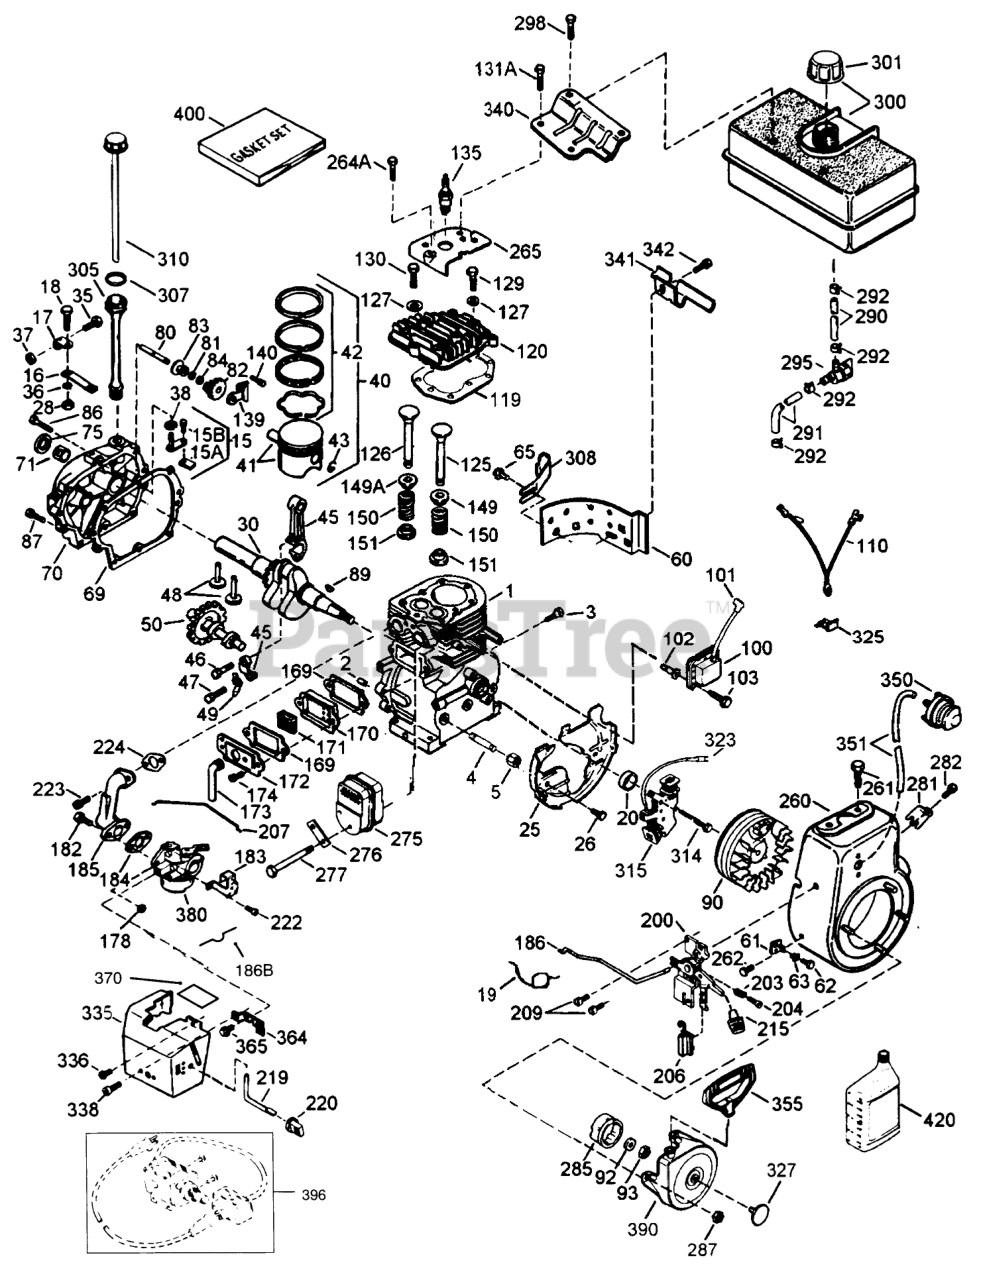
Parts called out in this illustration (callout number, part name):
1	Cylinder Asm (Incl. Ref. #2, 20, & 72)
2	Pin-Dowel
3	Screw (1/4-20x1/2)
4	Nipple-Pipe
5	Cap-Pipe
15	Governor (Incl. Ref. #15A & 15B)
15A	Yoke-Governor
15B	Screw (6-40x5/16)
16	Lever-Governor
17	Clamp-Lever, Governor
18	Screw
19	Spring-Throttle
20	Seal-Oil
25	Baffle-Housing, Blower
26	Screw (1/4-20x19/32)
28	Nut-Lock
30	Crankshaft
36	Washer-Lock
37	Nut-Lock
38	Ring-Retaining
40	Piston, Pin & Ring Set (Std.)
40	Piston, Pin & Ring Set (.010" OS)
40	Piston, Pin & Ring Set (.020" OS)
41	Piston & Pin Asm (Std.) (Incl. Ref. #43)
41	Piston & Pin Asm (.010" OS) (Incl. Ref. #43)
41	Piston & Pin Asm (.020" OS) (Incl. Ref. #43)
42	Ring Set (Std.)
42	Ring Set (.010" OS)
42	Ring Set (.020" OS)
43	Ring-Retaining, Piston Pin
45	Connecting Rod Asm (Incl. Ref. #46, 47, & 49)
46	Bolt-Rod
47	Bolt-Rod
48	Lifter-Valve
49	Dipper-Oil
50	Camshaft (MCR)
60	Extension-Housing, Blower
61	Bracket
62	Screw (8-32 x 3/8)
63	Grommet
69	Gasket-Cover, Cylinder
70	Cylinder Cover (Incl. Ref. #71, 75, & 80)
71	Bushing-Crankshaft
75	Seal-Oil
80	Shaft-Governor
81	Washer-Flat
82	Governor Gear Asm (Incl. Ref. #81)
83	Spool-Governor
84	Ring-Retaining
86	Screw (1/4-20x1-3/16)
87	Screw (1/4-20x1-11/16)
89	Key-Flywheel
90	Flywheel ASM
92	Washer-Belleville
93	Nut-Flywheel
100	Solid State ASM
101	Cover-Spark Plug
102	Stud
103	Screw (T-15, 10-24 x 15/16)
110	Ground Wire
119	Gasket-Head, Cylinder
120	Head-Cylinder
125	Exhaust Valve (Std.) (Incl. Ref. #151)
125	Exhaust valve (1/32" OS) (Incl. Ref. #151)
126	Intake Valve (Std.) (Incl. Ref. #151)
126	Intake Valve (1/32" OS) (Incl. Ref. #151)
127	Washer-Flat
129	Screw (5/16-18x1-25/32)
130B	Screw (5/16-18x1-1/2)
131A	Screw
135	Spark Plug-Resistor (R J19 L M)
139	Bracket-Gear, Governor
140	Screw (10-24x1/2)
149	Cap-Spring, Valve
149A	Cap-Spring, Valve
150	Spring-Valve
151	Keeper-Spring, Valve
169	Gasket-Cover, Valve
170	Body-Breather
171	Element-Breather
172	Cover-Valve
173	Tube-Breather
178	Nut and Lock Washer (1/4-28)
182	Screw (1/4-28x1)
183A	Bracket-Choke
184	Gasket-Carburetor To Intake Pipe
185	Pipe-Intake
186	Link-Governor
186A	Spring-Choke
200	Control Bracket (Incl. Ref. #19, 203, 204 & 206)
203	Spring-Compression
204	Screw
206	Terminal
207	Link-Throttle
209	Screw (10-32 x 1/2)
215	Knob-Control
219	Rod-Choke
220	Knob-Control
222	Screw (10-32 x 1/2)
223	Screw (T-30, 5/16-18x1-3/32)
224	Gasket-Pipe, Intake
260	Housing-Blower
261	Screw (5/16-18x3/4)
264A	Screw (1/2-20x5/8)
265	Cover-Cylinder Head
275	Muffler
276	Plate-Locking
277	Screw (T-15, 10-24 x 15/16)
282	Screw (8-32 x 3/8)
285	Cup-Starter
287	Nut and Lock Washer (1/4-28)
290	Line-Fuel (8.62)
291	Line-Fuel
292	Clamp-Line, Fuel
295	Valve-Shut Off, Fuel
298	Screw (1/4-15x7/8)
300	Fuel Tank (Incl. Ref. #292 & 301)
301	Cap-Fuel
305	Tube-Fill, Oil
308	Clip-Tube, Fill
310	Gauge Oil ASM
314	Screw (1/4-20 x 3/4)
315	Alternator Coil (18 Watt) (Incl. Ref. #323)
323	Terminal
325	Clip-Wire
327	Plug Starter
335	Cover-Carburetor
336	Screw (10-32x1/2)
338	Screw (10-32 x 3/8)
340	Bracket-Tank, Fuel
341	Bracket-Tank, Fuel (Black)
342	Screw (1/4-20x19/32)
350	Primer-Asm
351	Line-Primer
355	Handle-Starter, Mitten Grip
364	Bracket-Carburetor
365	Screw (8-32x27/64)
380	Carburetor (Incl. Ref. #184)
390	Starter-Rewind
396	Starter-Electric (110 Volt)
400	Gasket Set
420	Oil-Engine (SAE 5W30)
